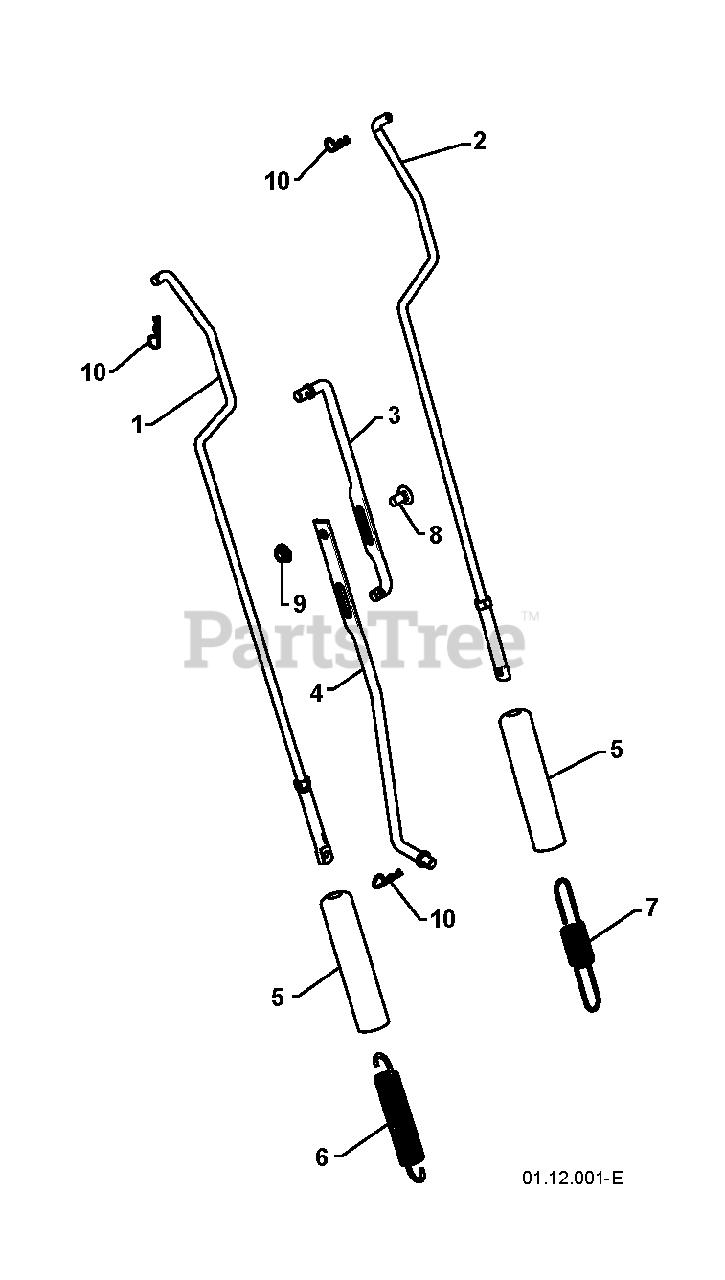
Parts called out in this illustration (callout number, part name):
1	ROD.IMPELLER
2	ROD.TRACTION
3	ROD, UPPER SPEED CONTROL
4	ROD, LOWER SPEED CONTROL.SNOW
5	SLEEVE, SPRING
6	SPRING.CONTROL.ROD.SNOW
7	SPRING.TRACTION.ROD.SNOW
8	BOLT
9	NUT.FLANGE.5/16
10	SPRING RETAINER
